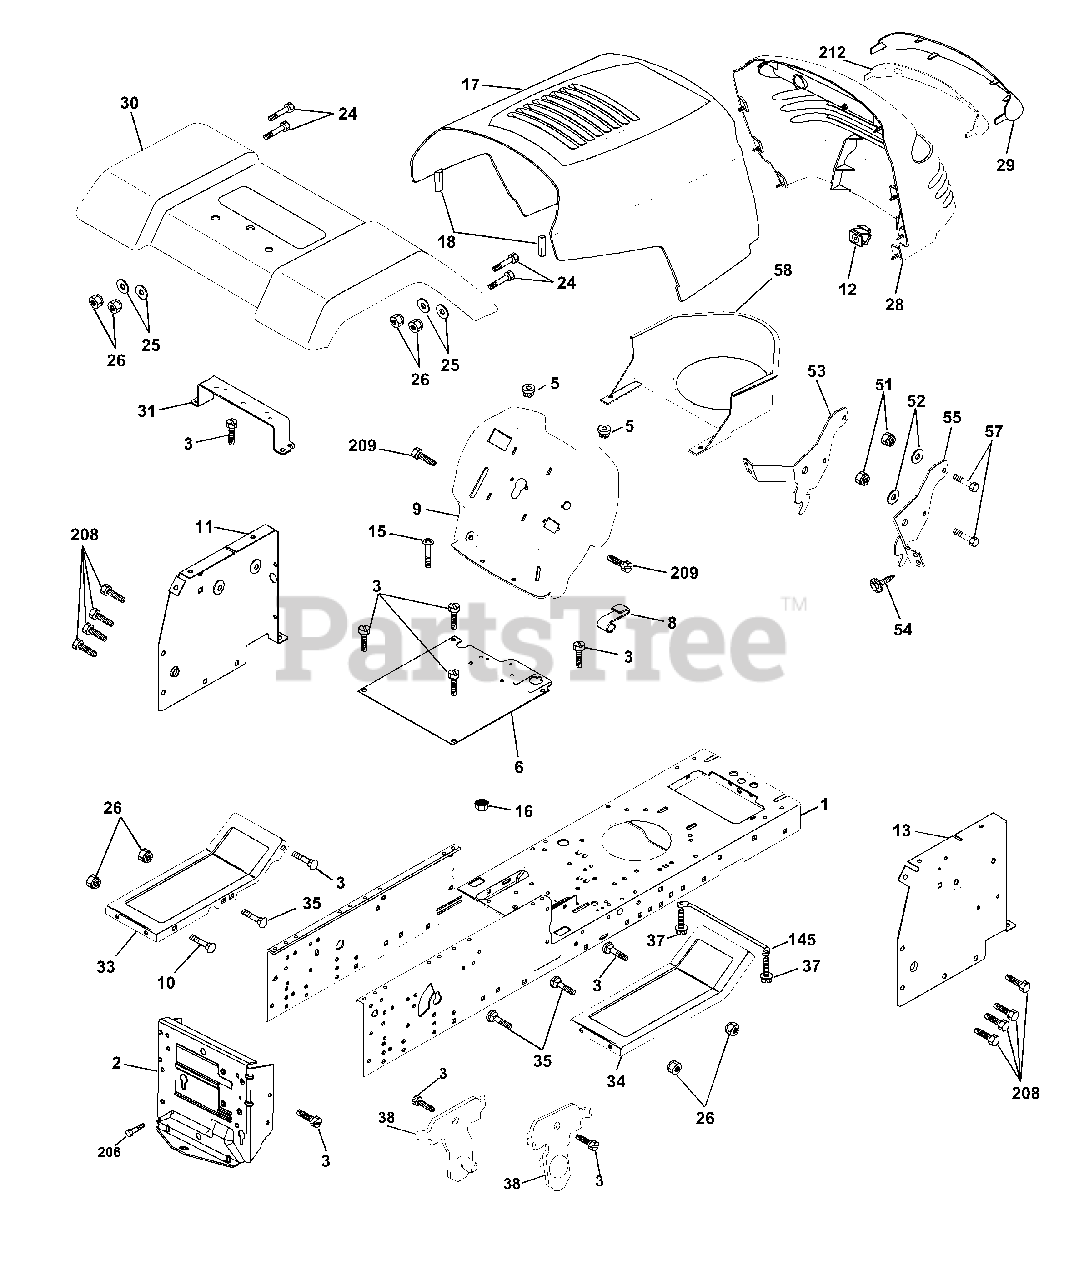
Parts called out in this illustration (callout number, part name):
2	Drawbar, Stretch
3	Screw 3/8-16 x 3/4
4	Washer 13/32 X 3/4 X 16 Ga.
5	Bumper, Hood/Dash
6	Saddle Silkscreen Flt Sdl
8	Clip Retainer Slide-On
9	Dash
10	Bolt, Carriage 3/8-16 x 1
11	Panel Dash LH
12	Clip Tinnerman Grille P.L
13	Panel Slkscr Dash RH
14	Screw Thdrol 3/8-16x1/2 Ty-tt
15	Screw Mach TRHD 5/16-18uncx3/4
16	Nut Keps 5/16-18 Unc
18	Bumper Hood
24	Bolt Fin Hex 3/8-16unc X 1 Gr. 5
25	Washer 13/32 X 13/16 X 12 Ga
26	Nut Lock Hex w/Ins 3/8-16 Unc
28	Grille P.L Ms 428
29	Lens Grille Private Label
31	Bracket Fender Repl 109873x
33	Footrest Pnt LH Perf
34	Footrest Pnt RH Perf
35	Bolt Rdhd Sht Sqnk 3/8-16 X3/4
37	Screw Thdrol 5/16-18 x 1/2 TYT
38	Bracket Asm. Pivot Mower Rear
51	Nut Lock W/Insert 1/4-20unc
52	Washer 9/32 x 7/8x16 Ga.
53	Bracket Grille Lh
54	Screw Hex 8-18 x 7/8
55	Bracket Grille Rh
57	Bolt Fin Hex 1/4-20 unc x .75
58	Duct Air Engine PL/LT
145	Rod Pivot Chassis/Hood
206	Bolt Shoulder 5/16-18
208	Screw Thdrol 3/8-16 x 1/2
209	Screw Hex Wsh Thdrol 3/8-16
